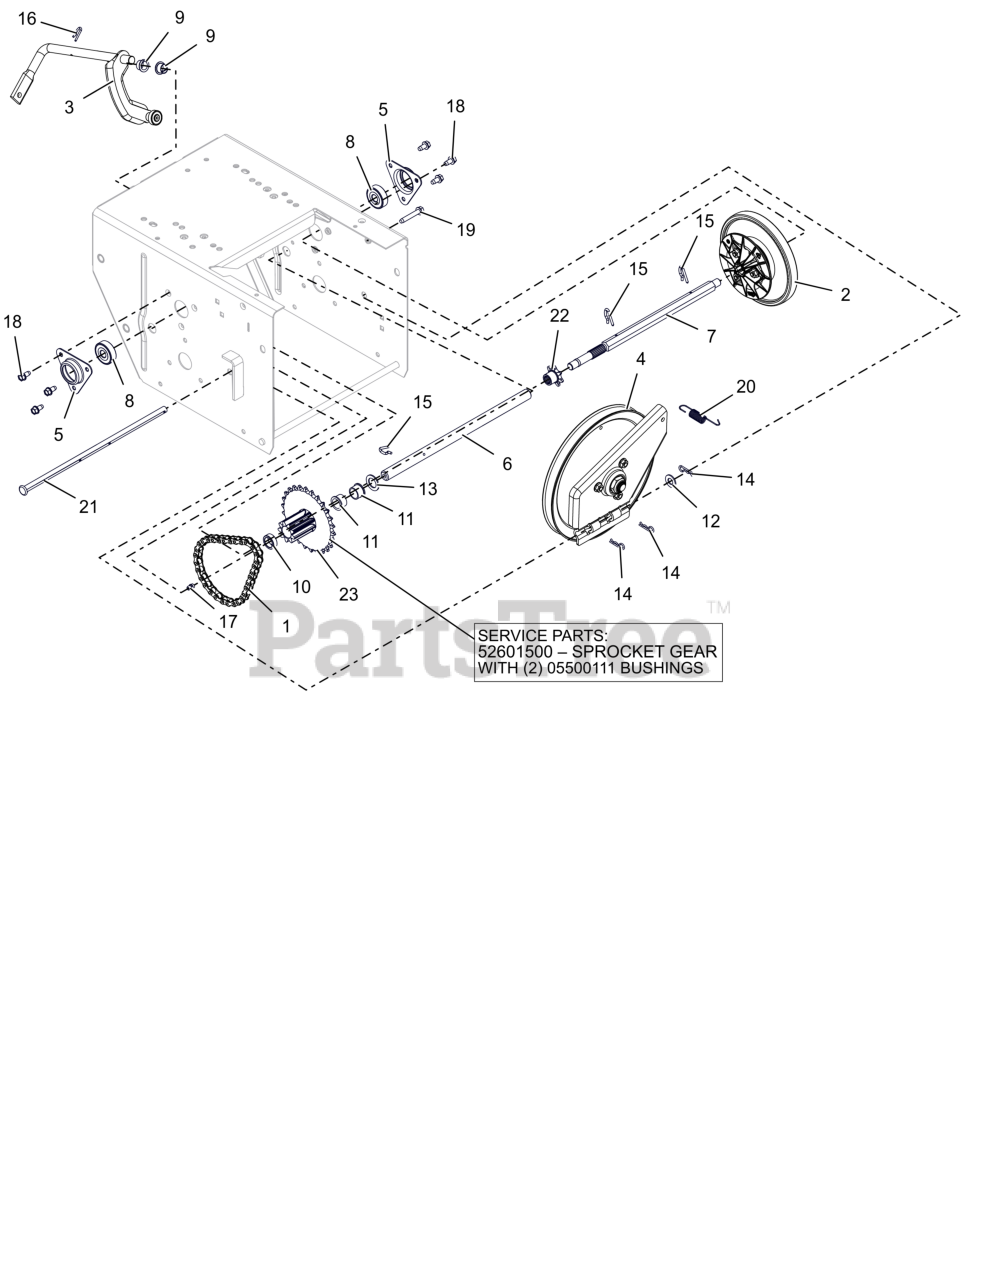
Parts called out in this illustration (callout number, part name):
1	CHAIN - #41, 32 PITCHES
2	DISC, FRICTION DRIVE-ASSEMBLY
3	ARM, SHIFT - ASSEMBLY
4	PLATE, SWING ASSEMBLY-DEEP
5	FLANGE, BEARING
6	SHAFT, PINION
7	SHAFT, HEX
8	BRG-BALL .437X1.375X.437
9	BUSHING, POLYLINER-.50 SPLIT
10	BSHG-SLV, .635X.880X.305
11	BSHG-FLG .625X.750X.500X.875
12	WSHR,FLT .406X.812X.065 ZCC
13	WSHR, FLT .630X1.005X.062 ZCC
14	PIN, HAIR #213 .08X1.19 ZCC
15	PIN, SPRING CLIP
16	CLIP, SPRING
17	ZERK,FITTING .25X.125 DRIVE IN
18	SCR-TAP .25-20X.50 HWH ZCC
19	SCR,TAP .25-20X1.50 HWH TR ZCC
20	SG-TENS .048X.50X2.8
21	PIN, PIVOT
22	SPROCKET- PINION 7T W/SPLINE
23	PINION & SPROCKET
